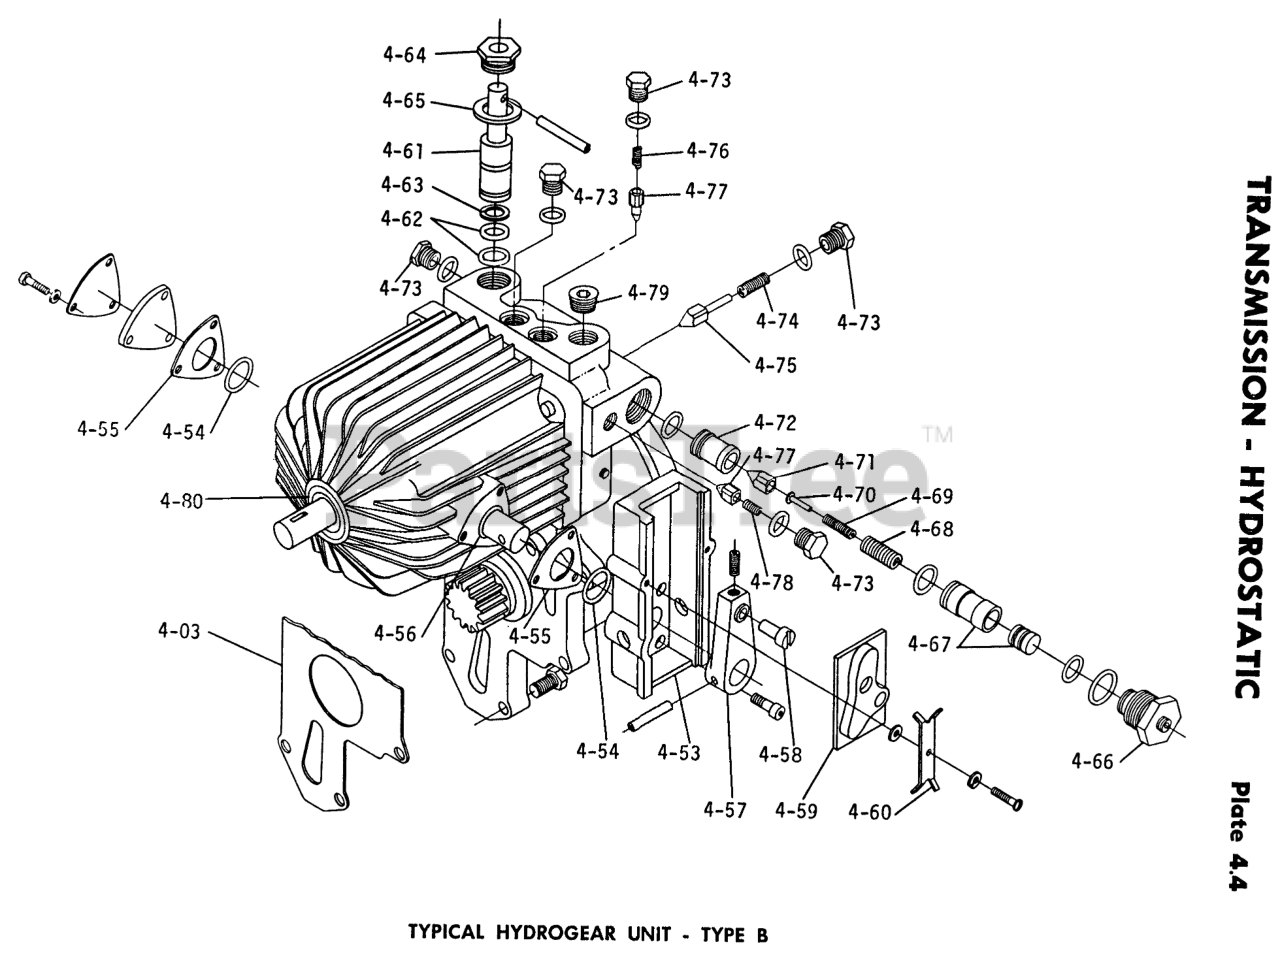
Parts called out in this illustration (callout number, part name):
4-57	Arm-Cam Follower
4-58	Set Screw-1/4-20 x 1/2
4-59	CAM
4-60	Screw #8-32 x 1/2
4-60	Lockwasher
4-60	Washer
4-61	SPIROL PIN
4-66	O RING
4-67	O RING
4-68	Spring Relief Valve
4-70	SPRING
4-73	O RING
4-74	SPRING-SUNDSTRAND
4-76	Spring Charge Pump Valve
